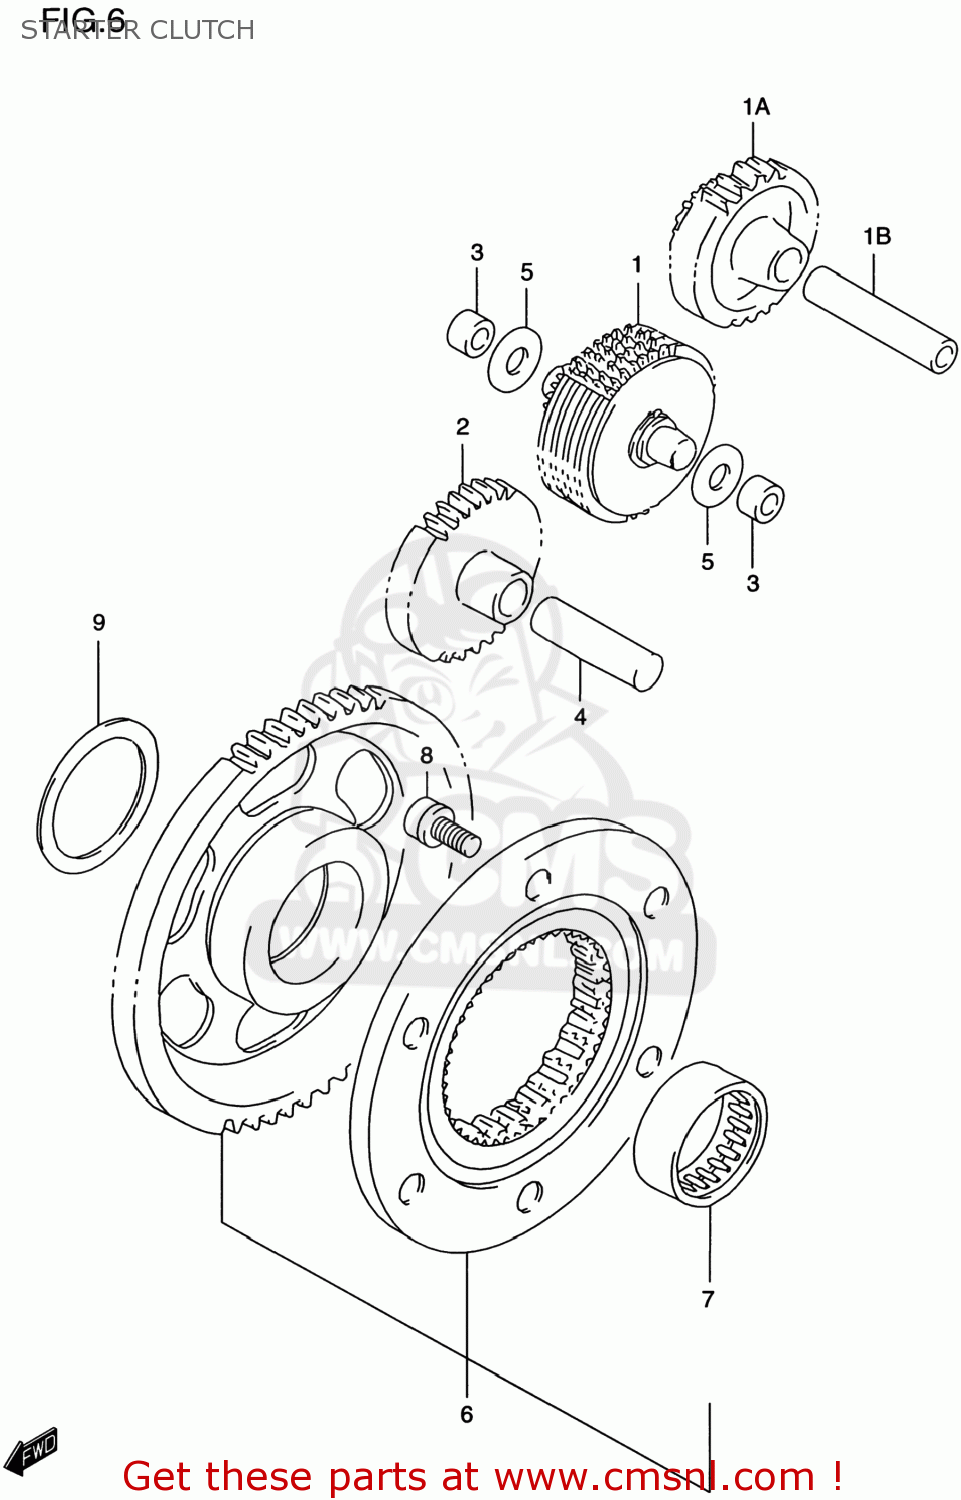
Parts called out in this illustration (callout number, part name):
1	LIMITER ASSEMBLY,STARTER IDLER GEAR
1A	GEAR,STARTER IDLE NO.1
1B	PIN(8X12X59)
2	GEAR,STARTER IDLE NO.2(NT:27)
3	BUSH,LIMITER GEAR SHAFT
4	PIN
5	WASHER
6	CLUTCH SET,STARTER
7	BEARING(31X39X17.8)
8	BOLT
9	SHIM
